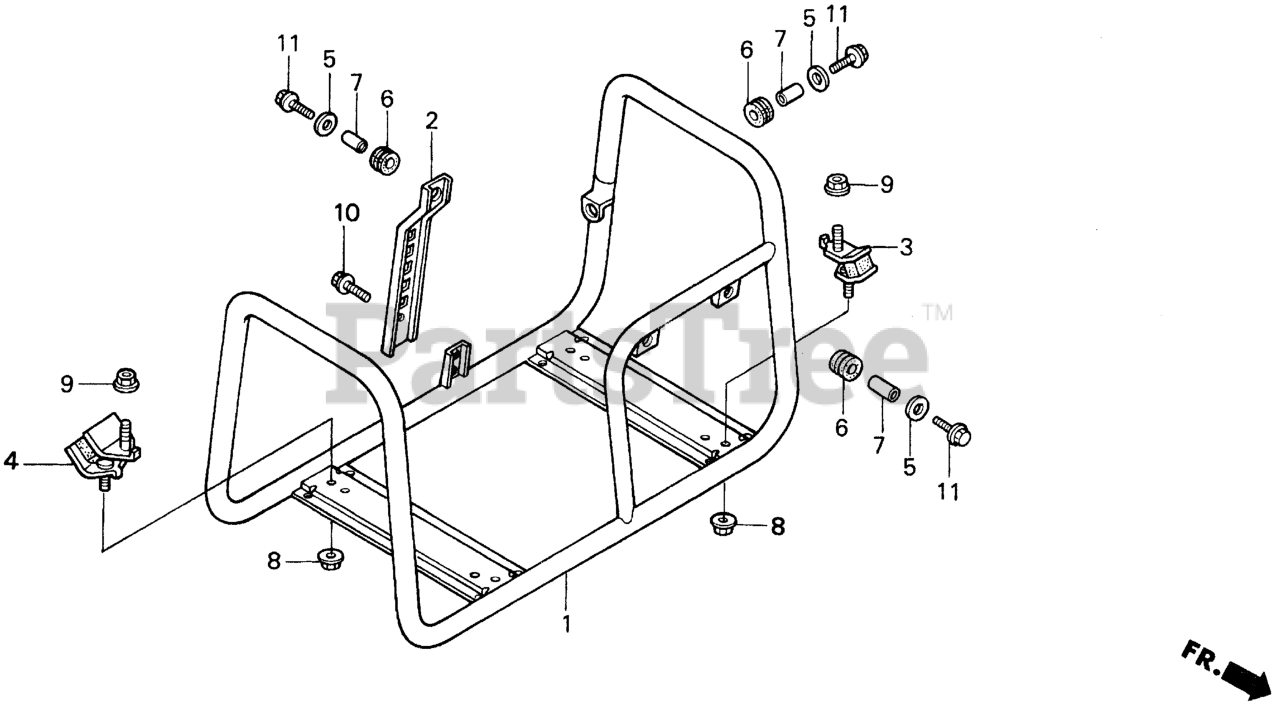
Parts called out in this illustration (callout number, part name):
1	FRAME *NH105* (MAT BLACK) (NOT AVAILABLE)
2	STAY, BOX SUPPORT
3	RUBBER (LOWER)
4	RUBBER (LOWER)
5	WASHER, AIR DUCT
6	RUBBER, CONTROL BOX
7	COLLAR, CONTROL BOX
8	NUT, FLANGE (8MM)
9	NUT, FLANGE (10MM)
10	BOLT, FLANGE (6X12) Use up to Engine SN 1543277.
11	BOLT, FLANGE (6X18)
